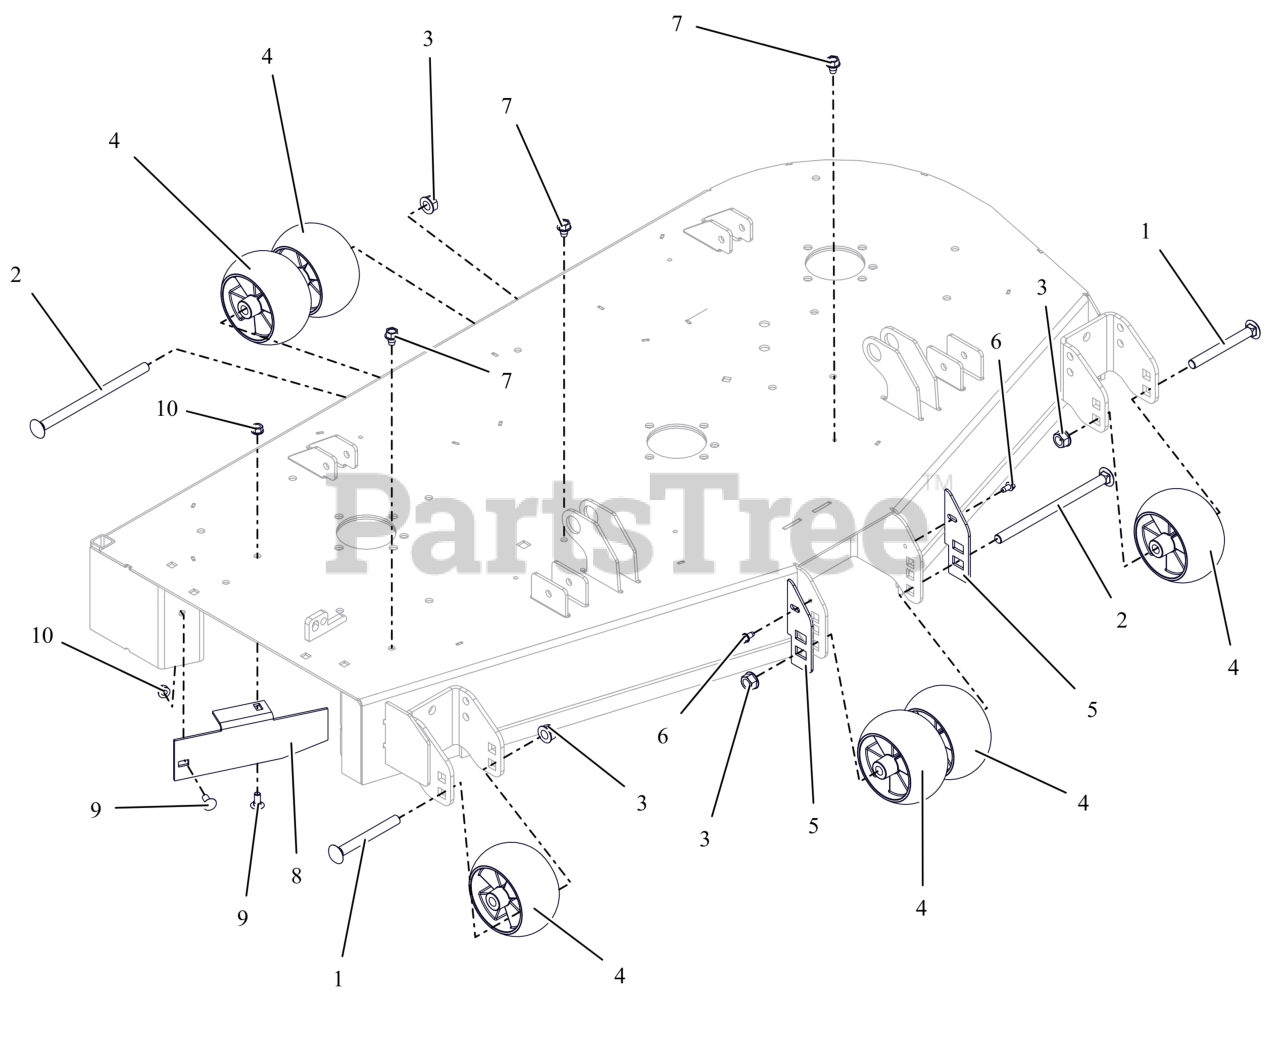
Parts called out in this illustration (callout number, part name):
1	BLT-RHNS .50-13X4.50 G5 ZCC NS
2	BLT-RHSN .50-13X8.00 G5 ZCC NS
3	NUT-LK-CTR-FLG .500-13 GG ZCC
4	WHEEL, ANTI SCALP - 5X3 CTR W/RIBS
5	PLATE, ANTI SCALP WHEEL 60" (ORANGE)
6	SCR-TAP .25-20X.50 HWH ZCC
7	SCR,TAP .375-16X.50 HWH TR ZCC
8	BAFFLE, DISCHARGE, 52"
9	BLT,RHSN .31-18X.75 G5 ZCC
10	NUT,LK-CTR-FLG .31-18 GF ZCC
